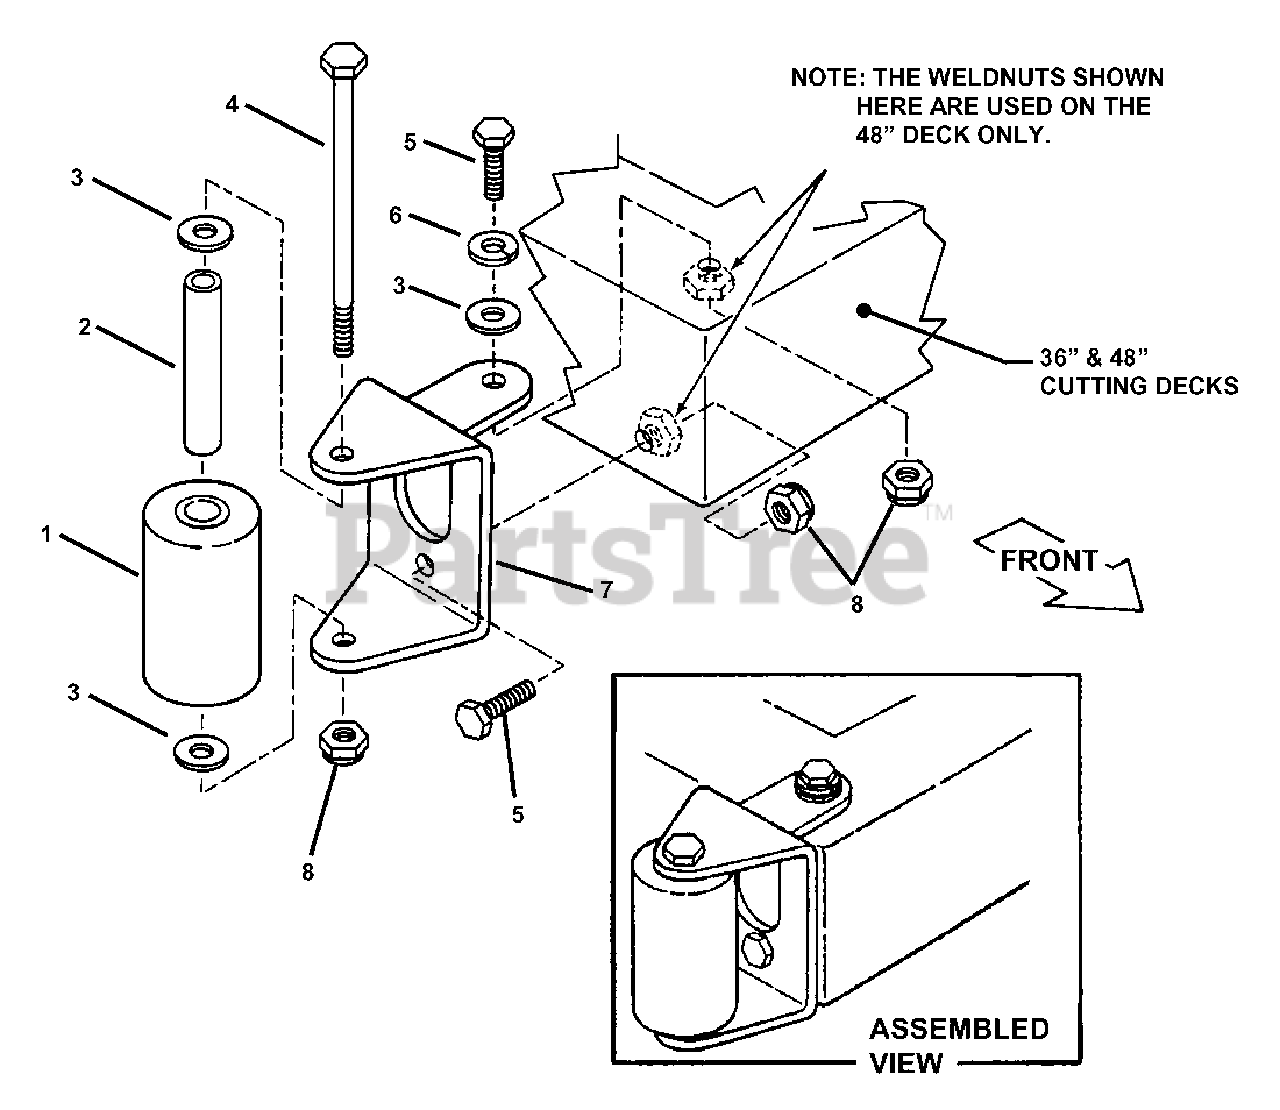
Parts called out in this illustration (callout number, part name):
1	ROLLER, Corner
2	SPACER, Roller
3	WASHER, 3/8" Flat
4	BOLT, 3/8-16 x 5-1/2" Hex Head Cap
5	SCREW, 3/8-16 x 1" Hex Head Cap, Grade 5
6	WASHER, 3/8" Split Lock
7	BRACKET, Roller
8	NUT, 3/8-16 Hex Nyloc
